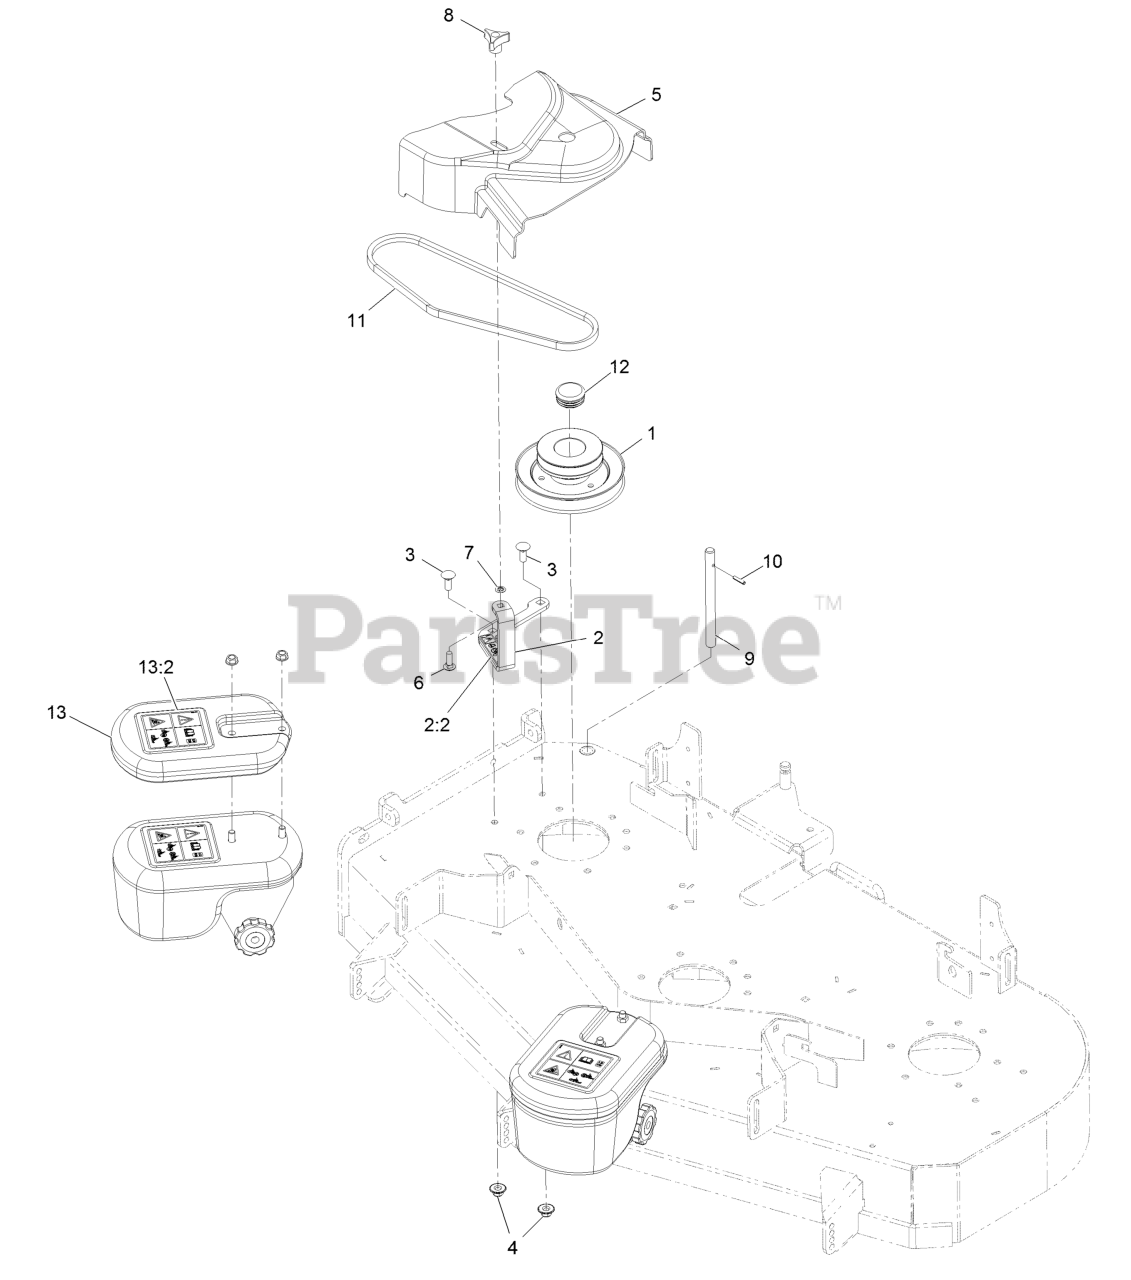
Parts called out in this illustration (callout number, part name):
1	Jackshaft-Uv Drive, 484 Splined
2	ASM-Cvr Brkt W/Decal
2:2	Decal-Danger
3	Bolt-Carriage 3/8-16 X 1
4	Nut-Nyloc 3/8-16 Flg
5	Cover-Belt, Uv 48
6	Bolt-Carriage 5/16-18 X 1
7	Ring-Bolt Retaining
8	Knob-3 Prong
9	Shaft-Catcher, Grass
10	Rollpin 3/16 X 7/8
11	Belt-Uv E 48
12	Plug-Round Plastic
13:2	Decal-Warning, Traction
